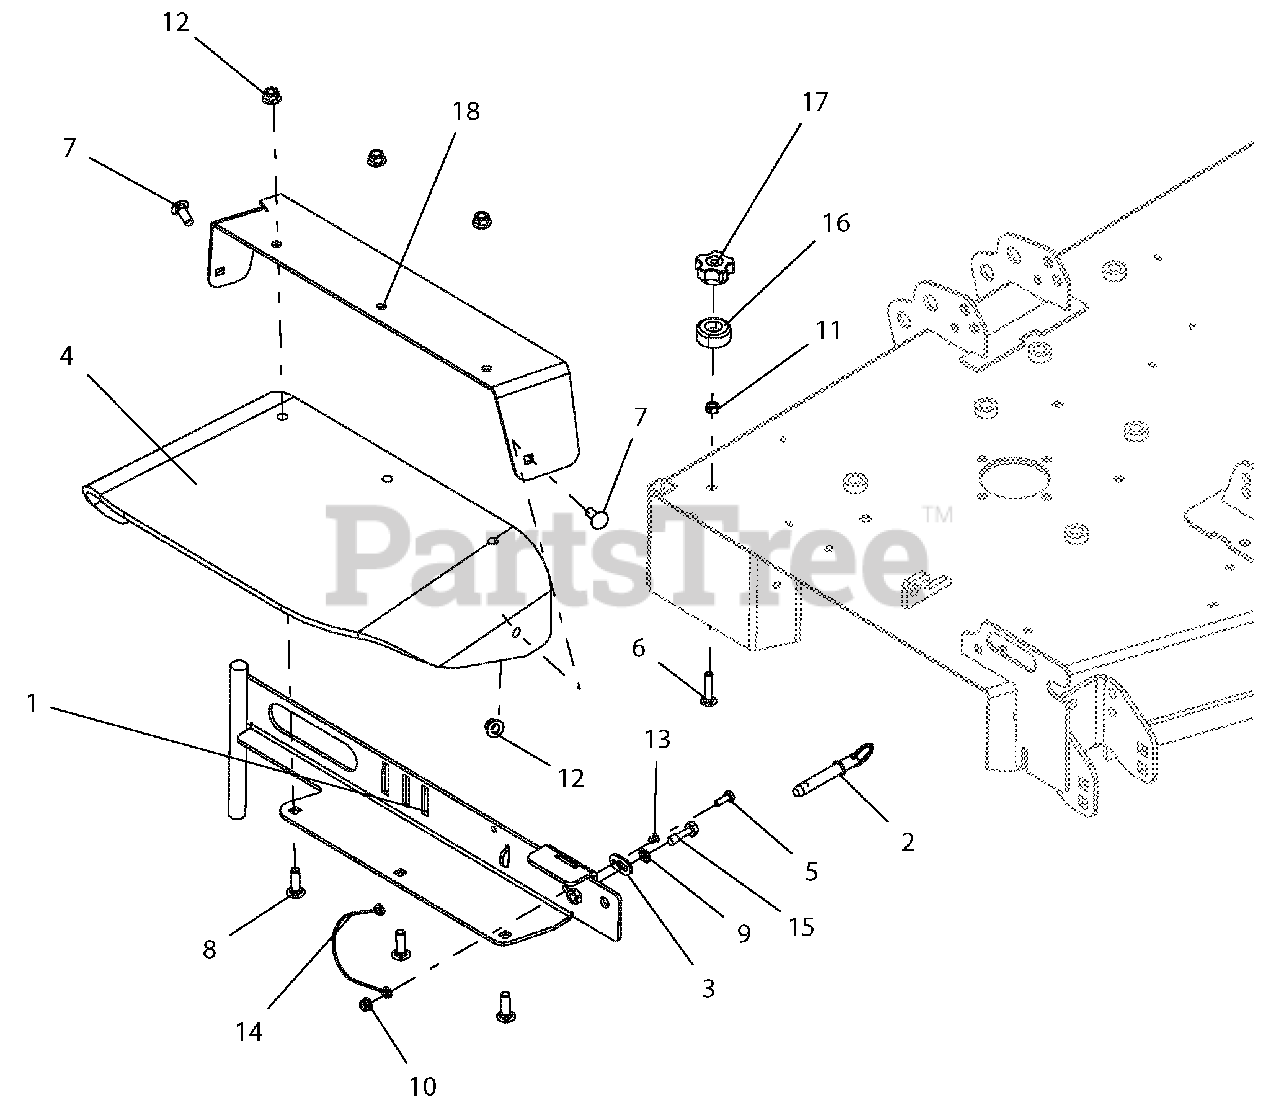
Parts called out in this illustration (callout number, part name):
1	WLDMT, 52" DISCHARGE CHUTE MTG-CE
2	PIN, .50 X 2.00 USABLE LG BALL
3	KEEPER, BOLT
4	CHUTE, RUBBER DISCHARGE
5	BLT-HEX .25-20X.75 GR5 YWZC
6	BLT-RDHDSQNK .31-18X1.50 G5 YWZC
7	BLT-RDHDSQNK .38-16X1.00 G5 YWZC
8	BLT-RDHDSQNK .38-16X1.25 G5 YWZC
9	LOCK, WSHR-EXT 0.391 X 0.628 X 0.036 YWZC
10	NUT-LK-NYL-FLG .25-20 YWZC
11	NUT-LK-CTR .31-18 YWZC
12	NUT-LK-NYL-FLG .38-16 YWZC
13	RVT-POP .187x.250 (#64) YWZC
14	LANYARD, 12"
15	BLT-HEX .38-16X1.25 GR5 CAP .37
16	BUMPER, RECESSED 1.50 X .63 W/.31 HOLE
17	KNOB, CLAMPING
18	KIT, PT DISCH CHUTE SUPT W/SAFETY DECALS-RED
